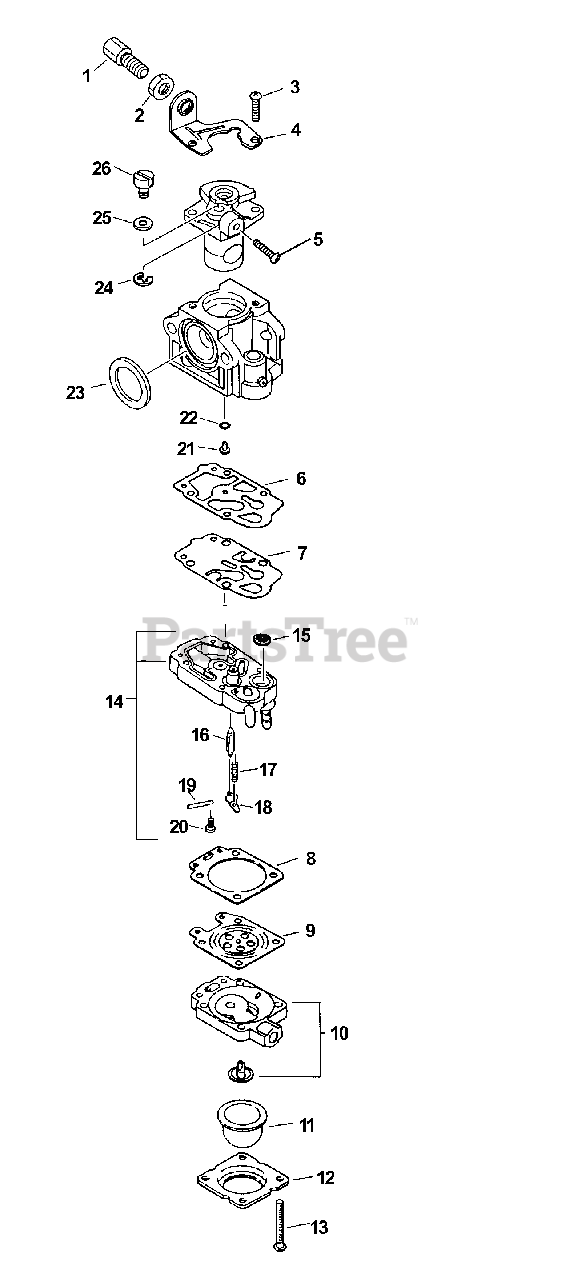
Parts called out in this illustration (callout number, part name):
1	ADJUSTER, THROTTLE CABLE
2	NUT, ADJUSTER LOCK M7
4	BRACKET, THROTTLE CABLE
6	GASKET, PUMP
7	DIAPHRAGM, PUMP
8	GASKET, METERING
9	DIAPHRAGM, METERING
10	BODY ASSY, PURGE
11	BULB, PURGE
12	RETAINER, PURGE BULB
14	BODY ASSY, PUMP
15	STRAINER
16	VALVE, INLET NEEDLE
17	SPRING, METERING LEVER
18	LEVER, METERING
19	PIN, METERING LEVER
21	JET, MAIN
23	SEAL
